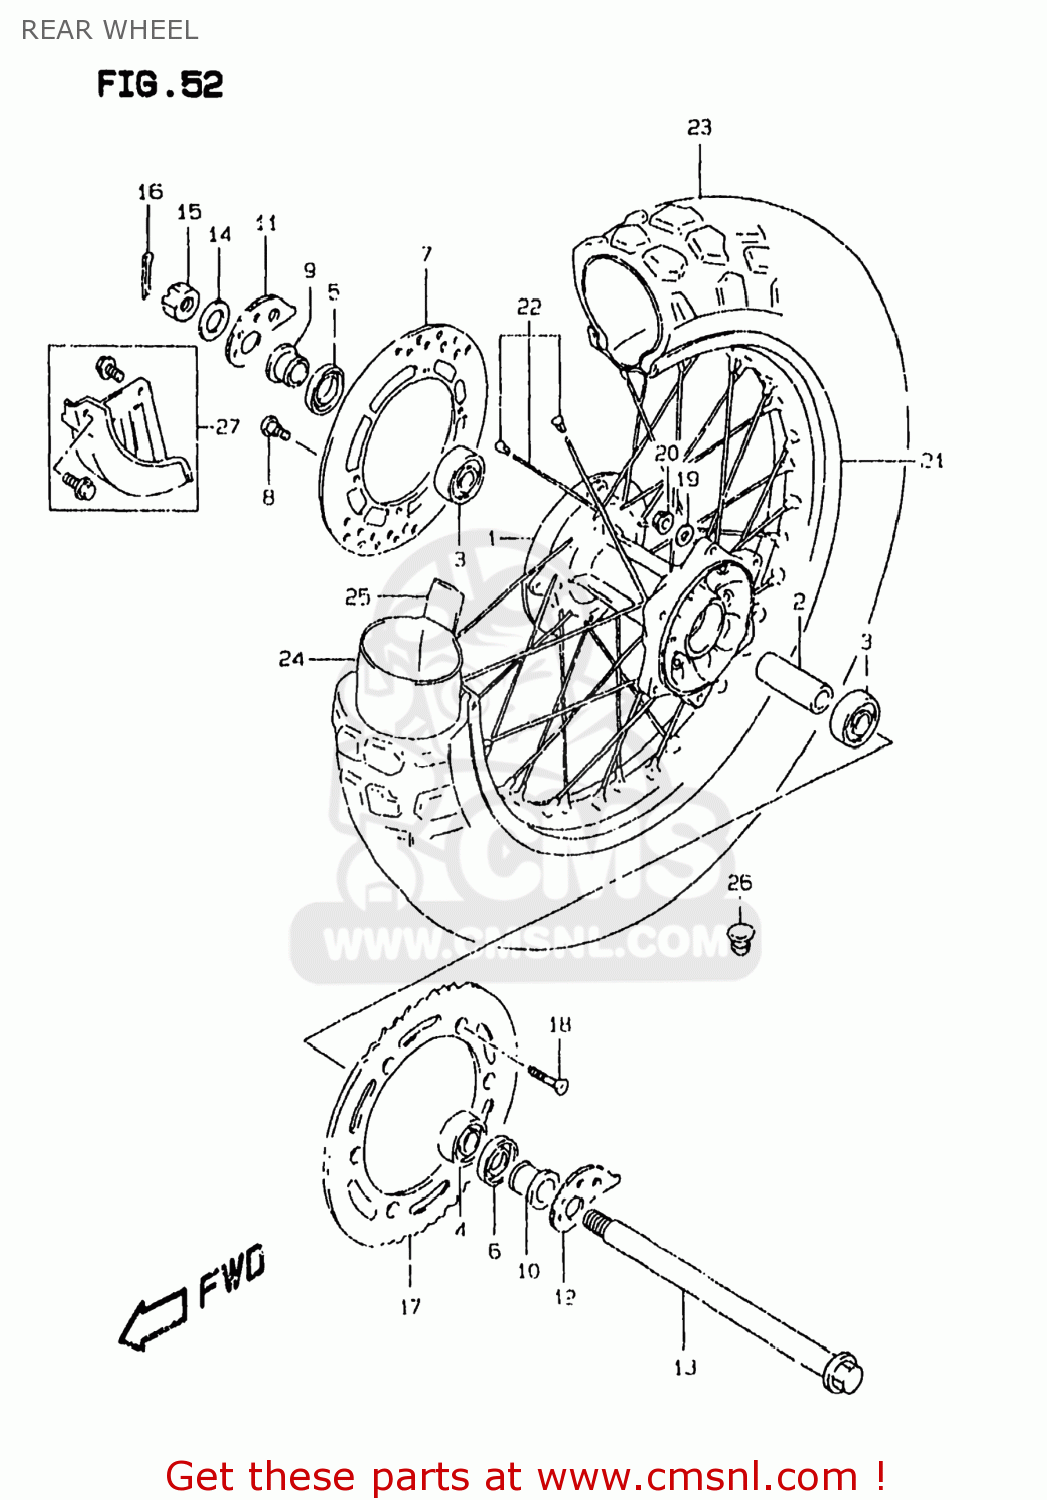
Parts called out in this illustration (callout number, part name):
1	HUB,RR WHEEL
2	SPACER,RR HUB BEARING
3	BALL BEARING
4	BEARING
5	SEAL,OIL(26X42X8)
6	SEAL,OIL(26X47X5)
7	DISC,RR BRAKE
8	BOLT,BRAKE DISC
9	SPACER,RR AXLE,R
10	SPACER,RR AXLE,L
11	ADJUSTER,CHAIN,R
12	ADJUSTER,CHAIN,L
13	AXLE,RR
14	WASHER(19X32X3.2)
15	NUT
16	PIN,COTTER
17	SPROCKET,RR(NT:41)
18	SCREW(8X33.5)
19	WASHER
20	NUT
21	RIM,REAR WHEEL (2.15X18)
22	SPOKE SET,RR WHEEL
23	TIRE,RR(110/90 18)
24	TUBE ASSEMBLY,WHEEL,INNER
25	PROTECTOR,WHL INR TUBE
26	CAP(OD:12)
27	COVER SET,RR BRAKE DISC
